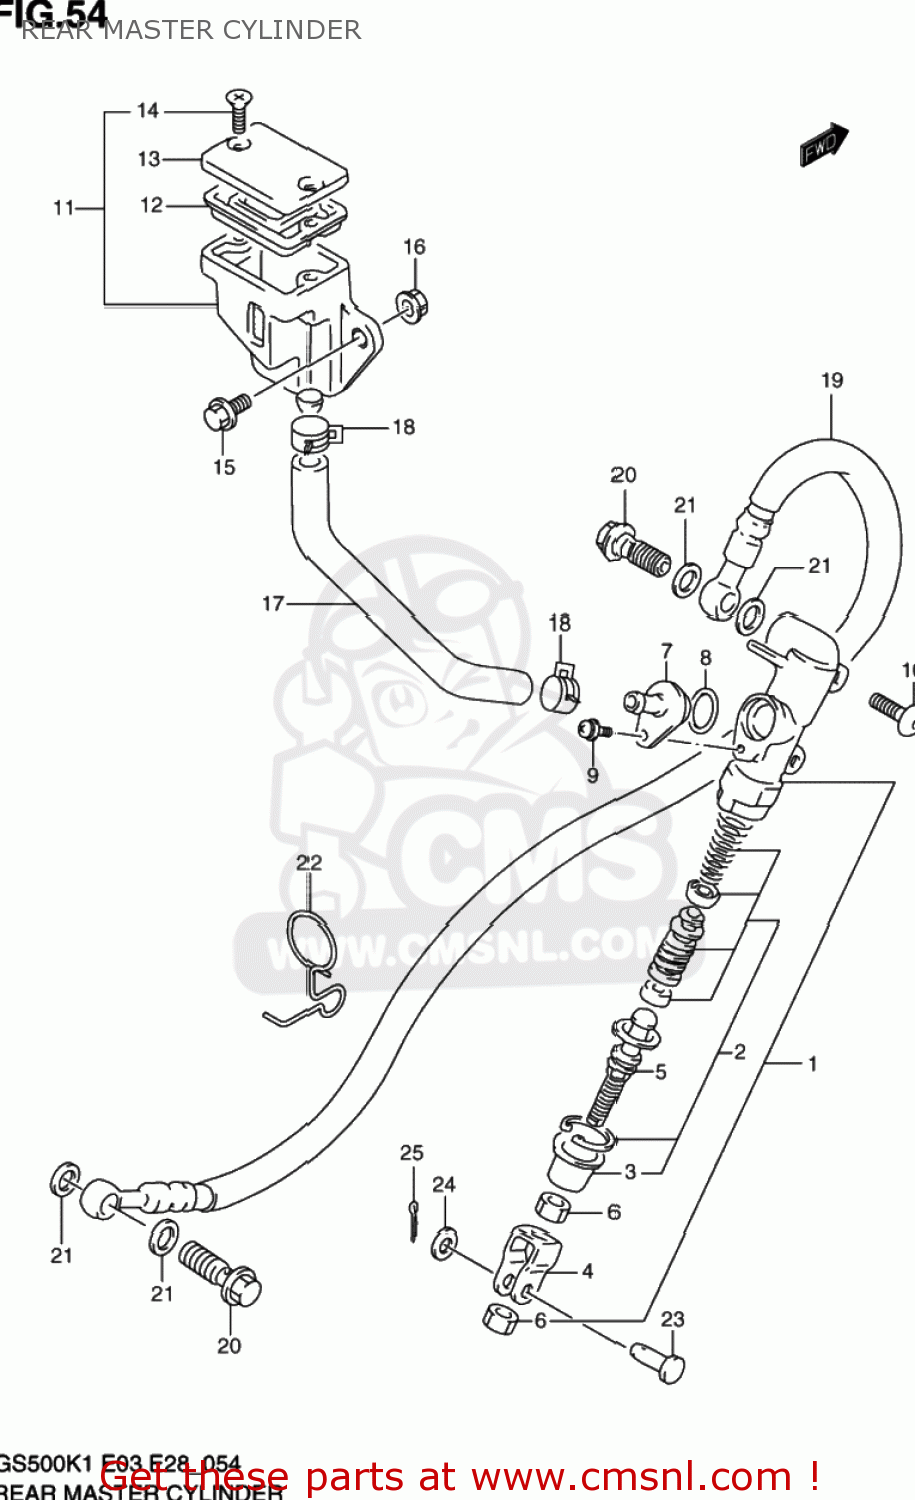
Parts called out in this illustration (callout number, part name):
1	CYLINDER ASSY,RR MASTER
2	PISTON/CUP SET
3	BOOT
4	YOKE
5	ROD,PUSH
6	NUT
7	CONNECTOR
8	O RING
9	SCREW
10	SCREW(6X25)
11	TANK ASSY,RR RESERVOIR
12	DIAPHRAGM
13	CAP
14	SCREW
15	BOLT
16	NUT
17	HOSE,RESERVOIR TANK
18	CLIP
19	HOSE,RR BRAKE
20	BOLT UNION
21	WASHER(10X15X1.5)
22	GUIDE,RR BRAKE HOSE
23	PIN
24	WASHER
25	PIN
